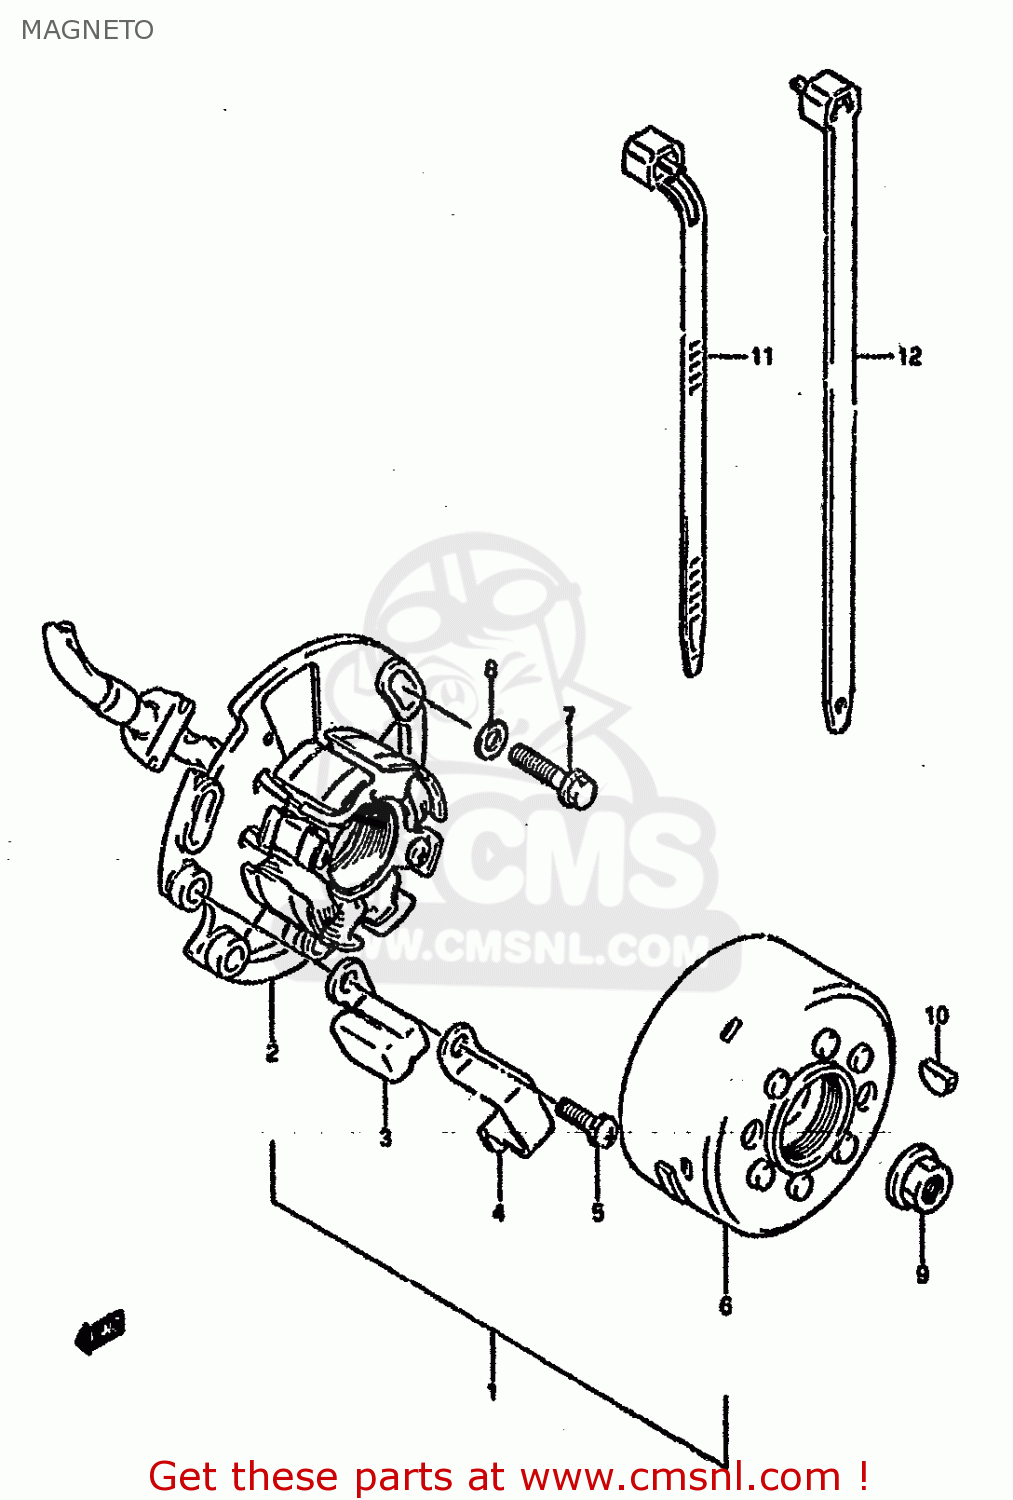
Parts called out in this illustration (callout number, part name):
1	MAGNETO ASSEMBLY
2	STARTER ASSY
3	COIL,PULSER
4	HOLDER,PICK UP COIL
5	SCREW
6	ROTOR ASSY
7	BOLT
8	WASHER
9	NUT
10	KEY
11	CLAMP(L:165)
12	CLAMP
